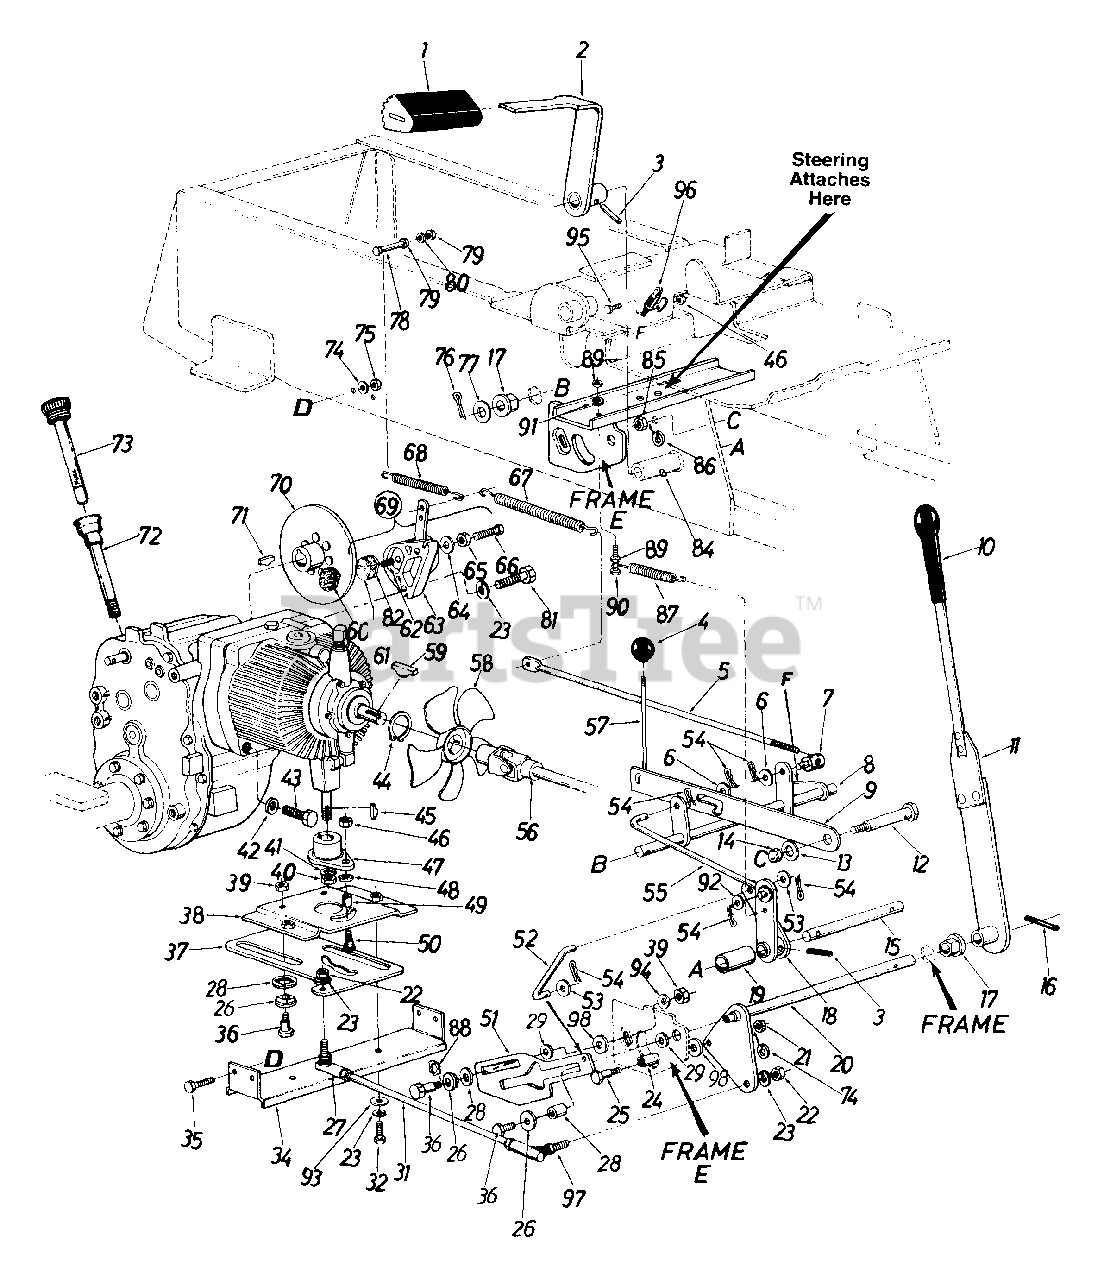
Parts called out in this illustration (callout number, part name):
4	Ball Knob - Brake
6	Fl-Wash. .375" I.D. x 1.00" O.D. x .030"
7	Ferrule
8	Brake Transfer Shaft Ass'y.
9	Parking Brake Cam
11	Control Arm Ass'y. Comp.
12	Shld. Bolt .62" Dia. x 2.75" Lg.
13	Fl-Wash. .460" I.D. x 1.24" O.D. x .06"
14	Push Speed Nut for .625" Dia. Shaft
15	Brake Pivot Shaft
16	Spring Pin Spiral 1/4" Dia. x 1.50" Lg.
17	Hex Flange Brg. Plastic .62" I.D.
18	Brake Hub Ass'y.
20	Control Handle Shaft Ass'y.
21	Hex Cent. L-Nut 5/16-18 Thd.
22	Hex Nut 3/8-24 Thd.
23	L-Wash. 3/8" I.D.
25	Shoulder Bolt
26	Fl-Wash. 7/16" I.D. x 1-3/8" O.D.
27	Ball Joint Ass'y. 3/8-24 Thd. - L H.
29	Fl-Wash. .325" I.D. x 1.25" O.D.
31	Tie Rod
32	Hex Bolt 3/8-16 x .75" Lg.
34	Support Channel
35	Hex Bolt 5/16-18 x .75" Lg.
36	Shld. Bolt .437" Dia. x .268"
38	Slide Mtg. Plate Ass'y.
39	Hex Cent. L-Nut 5/16-18 Thd.
40	Hex Nut 1/2-13 Thd.
41	L-Wash. 1/2" I.D.
42	Fl-Wash. .385" I.D. x .87" O.D. x .060"
43	Socket Hd. Scr. 3/8-16 x 2.75" Lg.
45	#5 Hi-Pro Key 1/8" x 5/8" Dia.
46	Hex Cent. L-Nut 1/4-20 Thd.
47	Pintle Plate Ass'y.
48	Fl-Wash. .281" I.D. x .50" O.D. x .063"
49	Needle Brg. .31" I.D. x .50" O.D. x .437" Lg.
50	Shld. Bolt .31" Dia. x .500
51	Neutral Control Slide
52	Neutral Control Rod
53	Fl-Wash. .312" I.D. x .630" O.D. x .063"
54	Hairpin Cotter
55	Brake Link Rod Ass'y.
56	Universal Joint Ass'y. Comp.
57	Parking Brake Link
58	Fan Ass'y.
59	#61 Hi-Pro Key 3/16 x 5/8" Dia.
60	Lining - Brake
61	Lining - Brake
63	Housing with Lever and Pin
64	Washer
65	Nut
66	Adjustment Pin
67	Extension Spring .50" O.D. x 6.5" Lg.
68	Extension Spring (Brake Return)
69	Disc Brake Ass'y. Comp.
70	Brake Disc Ass'y.
71	Hi-Pro Key 3/16 x 3/4" Dia.
72	Dipstick Tube Ass'y.
73	Dipstick Ass'y.
74	L-Wash. 5/16" I.D.
75	Hex Nut 5/16-18 Thd.
76	Cotter Pin 1/8" Dia. x 1.00" Lg.
77	Fl-Wash. .635" I.D. x 1.00" O.D. x .120" Thk.
78	Hex Scr. 1/4-20 x 2.50" Lg.
79	Hex Nut 1/4-20 Thd.
80	L-Wash. 1/4" I.D."
81	Hex Scr. 3/8-16 x 1.25" Lg.
82	Backing Plate
85	Hex Nut 7/16-20 Thd.
86	L-Wash. 7/16" I.D.
87	Extension Spring
88	Wave Wash.
89	Hex Nut 1/4-20 Thd.
90	Hex Bolt 1/4-20 x 1.25" Lg.
91	L-Wash. 1/4" I.D.
92	Fl-Wash.
93	Fl-Wash. .38" I.D. x 1.25" O.D.
95	Hex Bolt 1/4-20 x 1/2" Lg.
96	Safety Switch (Clutch)
97	Ball Joint Ass'y. 3/8-24 Thd. - R.H.
98	Fl-Wash. .32" I.D. x .6" O.D.
